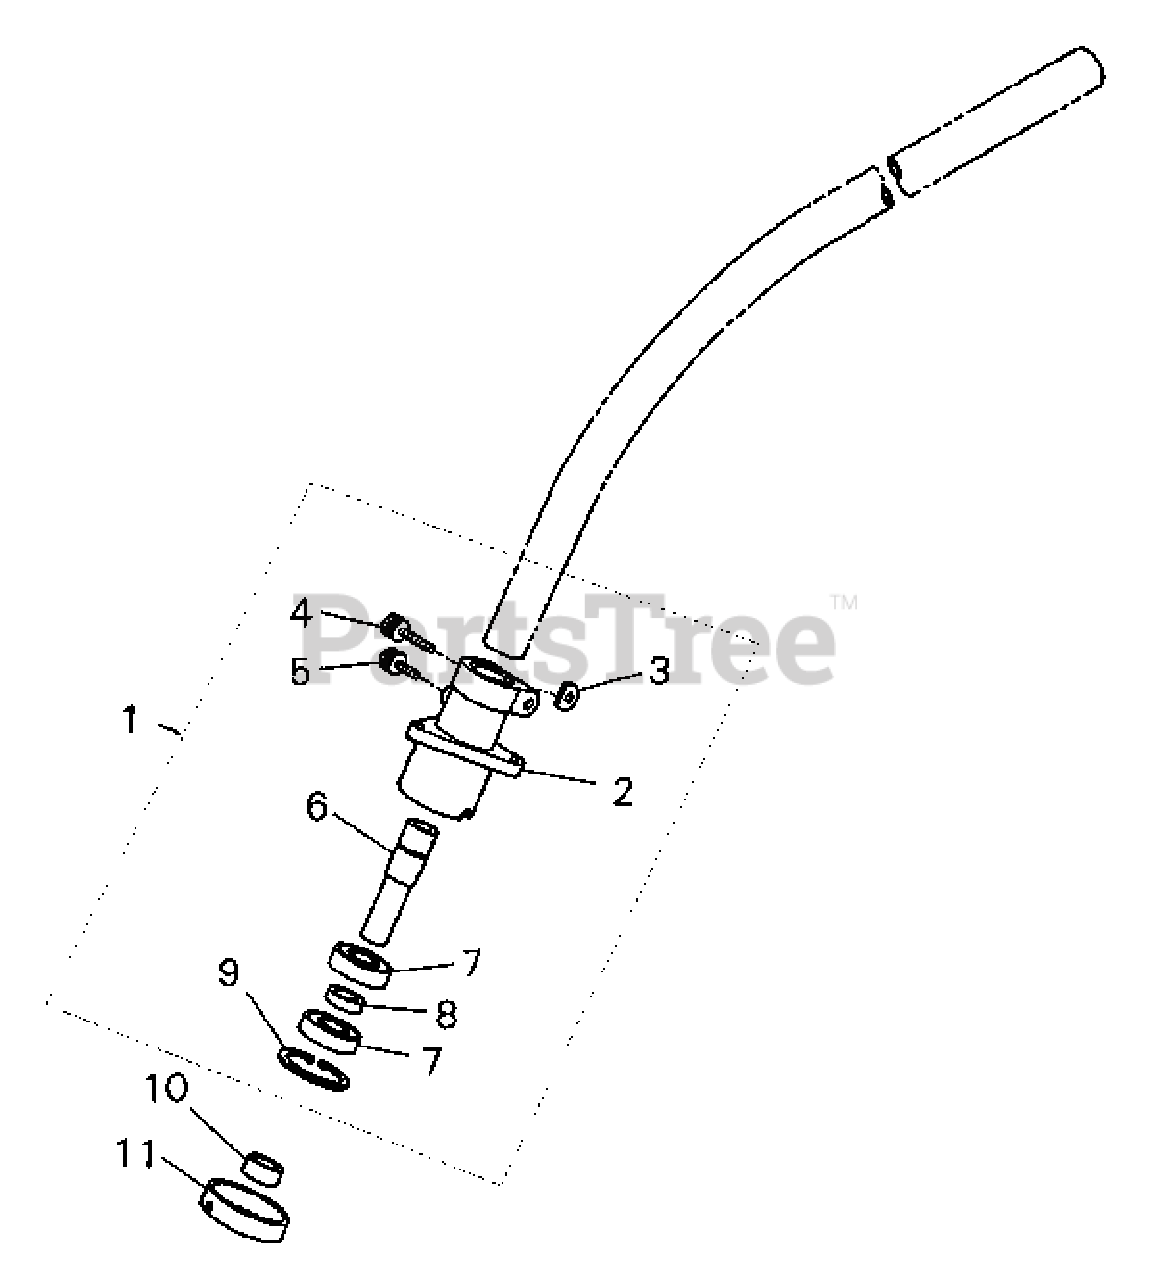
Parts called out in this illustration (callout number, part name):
1	SHAFT CASE ASSY
2	CASE, GEAR
3	SHIM
4	SCREW - 5X25
5	SCREW - 5X10
6	SHAFT
7	BEARING, BALL - 6001DDU
8	SPACER - UPPER
9	RING, RETAINING - 28
10	SPACER - LOWER
11	HOLDER
